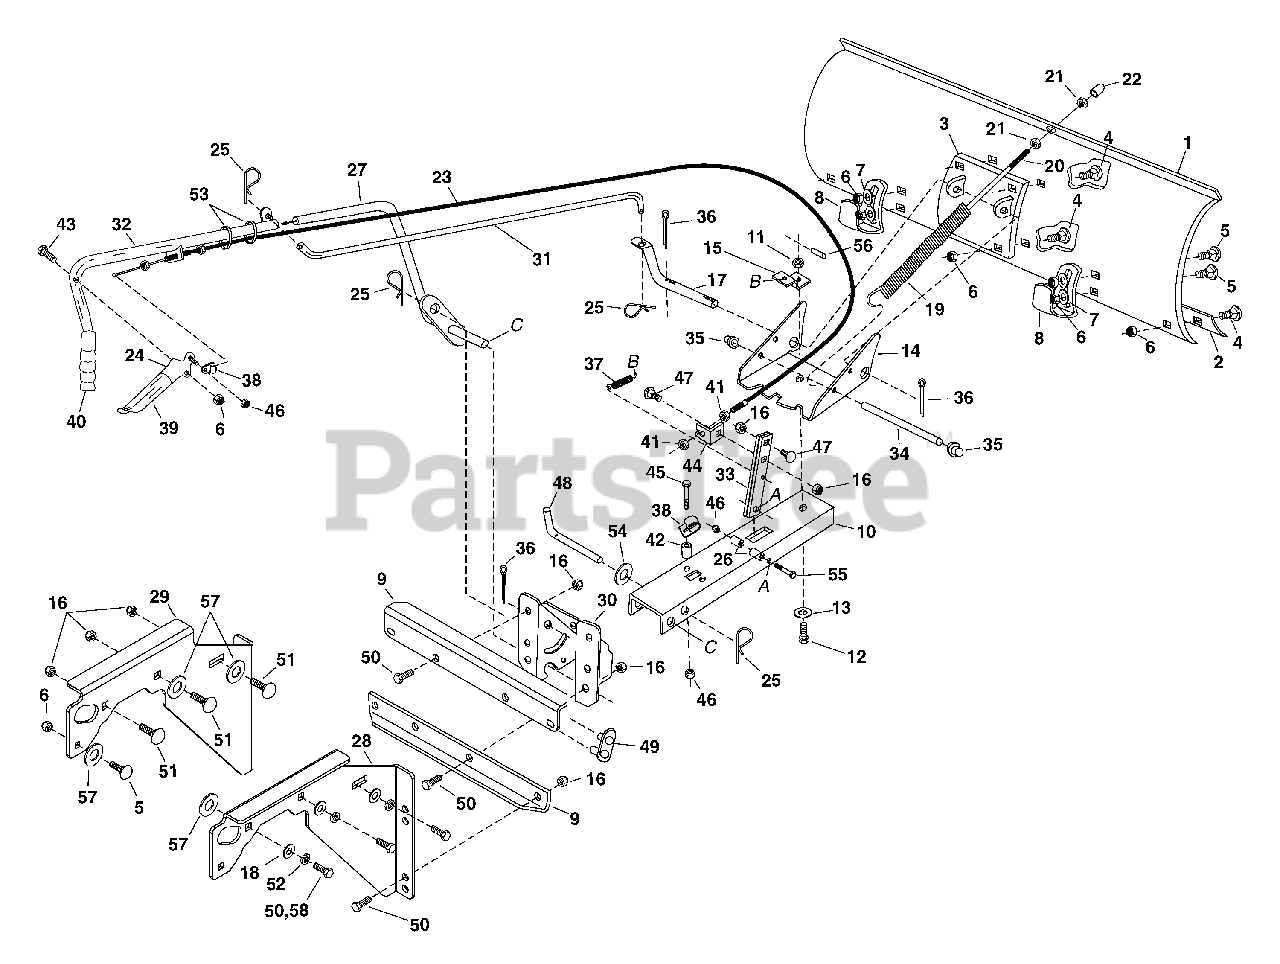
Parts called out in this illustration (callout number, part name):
1	Blade 48"
2	Wear Plate 48"
3	Reinforcement Plate Assembly
4	Bolt, Carriage 5/16-18 x 3/4"
5	Bolt, Carriage 5/16-18 x 1"
6	Nylock Nut, 5/16-18 Thread
7	Washer, 5/16"
8	Skid Shoe
9	Bracket, Angle Support
10	Push Channel
11	Hex Lock Nut, 1/2-13 Thread
12	Bolt, Special Pivot
13	Washer, Flat 1/2"
14	Plate, Pivot 7 Ga.
15	Bracket, Spring Mt.
16	Nylock Hex Nut, 3/8"
17	Shaft, Blade Pivot
18	Washer, 3/8" STD.
19	Spring, Blade Adjust
20	Hex Bolt, 3/8-16 x 3-1/2"
21	Hex Nut, 3/8-16 Thread
22	Plastic Cap
23	Control Cable Assembly
24	Release Grip Assembly
25	Pin, Hairpin Small 3/32"
26	Spacer, .28 ID x 1"
27	Lift Handle Rod Assembly
28	Hanger Bracket, R.H.
29	Hanger Bracket, L.H.
30	Pivot Support Bracket
31	Rod, Blade Pivot
32	Lift Handle Tube Assembly
33	Angle Lock Bar
34	Spring Mount Rod
35	Palnut, 3/8"
36	Cotter Pin 1/8" x 1-1/4"
37	Angle Lock Spring
38	Cable End Fitting
39	Grip, Plastic
40	Handle, Grip
41	Hex Jam Nut, 5/16-24 Thread
43	Hex Bolt, 5/16-18 x 1-1/2"
44	Cable Mount Bracket
45	Hex Bolt, 1/4-20 x 1-1/2"
46	Nylock Hex Nut, 1/4"
47	Carriage Bolt, 3/8-16 x 1-1/4"
48	Channel Pivot Pin
49	Lift Link Assembly
50	Hex Bolt, 3/8-16 x 1"
51	Carriage Bolt, 3/8-16 x 1"
52	Lock Washer 3/8"
53	Plastic Tie
55	Hex Bolt, 1/4-20 x 3-1/4" Lg. Gr 5
56	1/4" x 1" Spring Pin
57	Washer, 1/2" (Large)
58	Hex Bolt, 3/8" x 1" (Thd. Forming)
